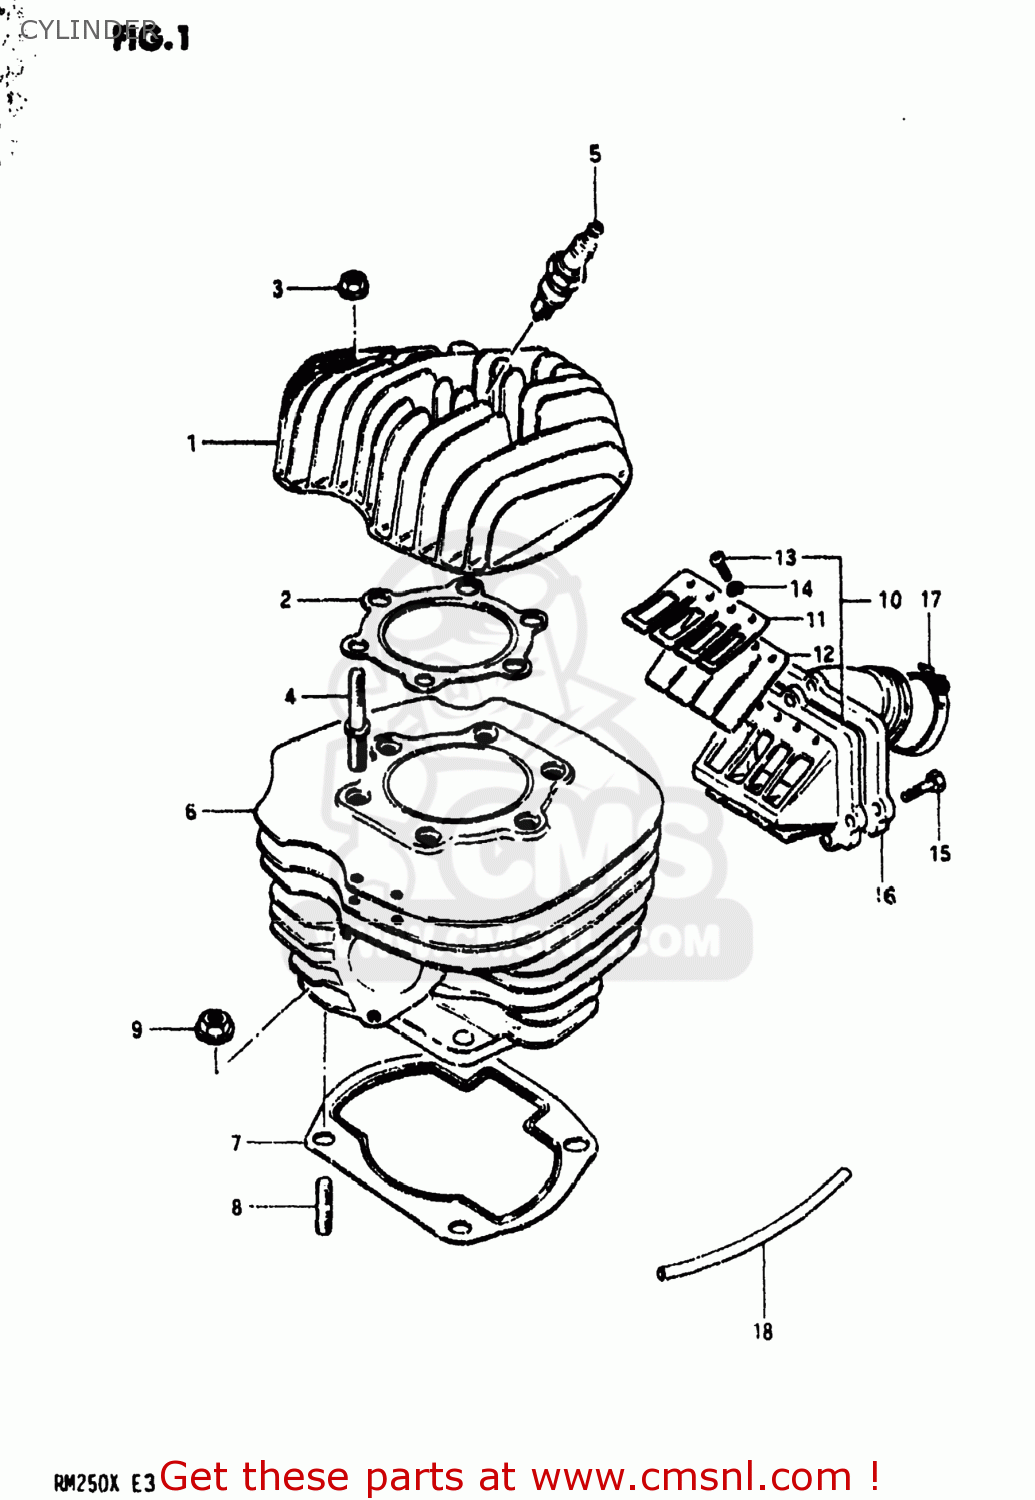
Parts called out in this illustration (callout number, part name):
1	HEAD,CYLINDER
2	GASKET,CYLINDER HEAD (NAS)
3	NUT
4	BOLT,STUD
5	SPARK PLUG N-2G CHMP
6	CYLINDER
7	GASKET,CYLINDER (MCA)
8	STUD 10X30
9	NUT
10	VALVE ASSEMBLY,REED
11	STOPPER,REED VALVE
12	VALVE,REED
13	SCREW
14	LOCK WASHER
15	BOLT
16	PIPE,INTAKE
17	CLAMP
18	HOSE
